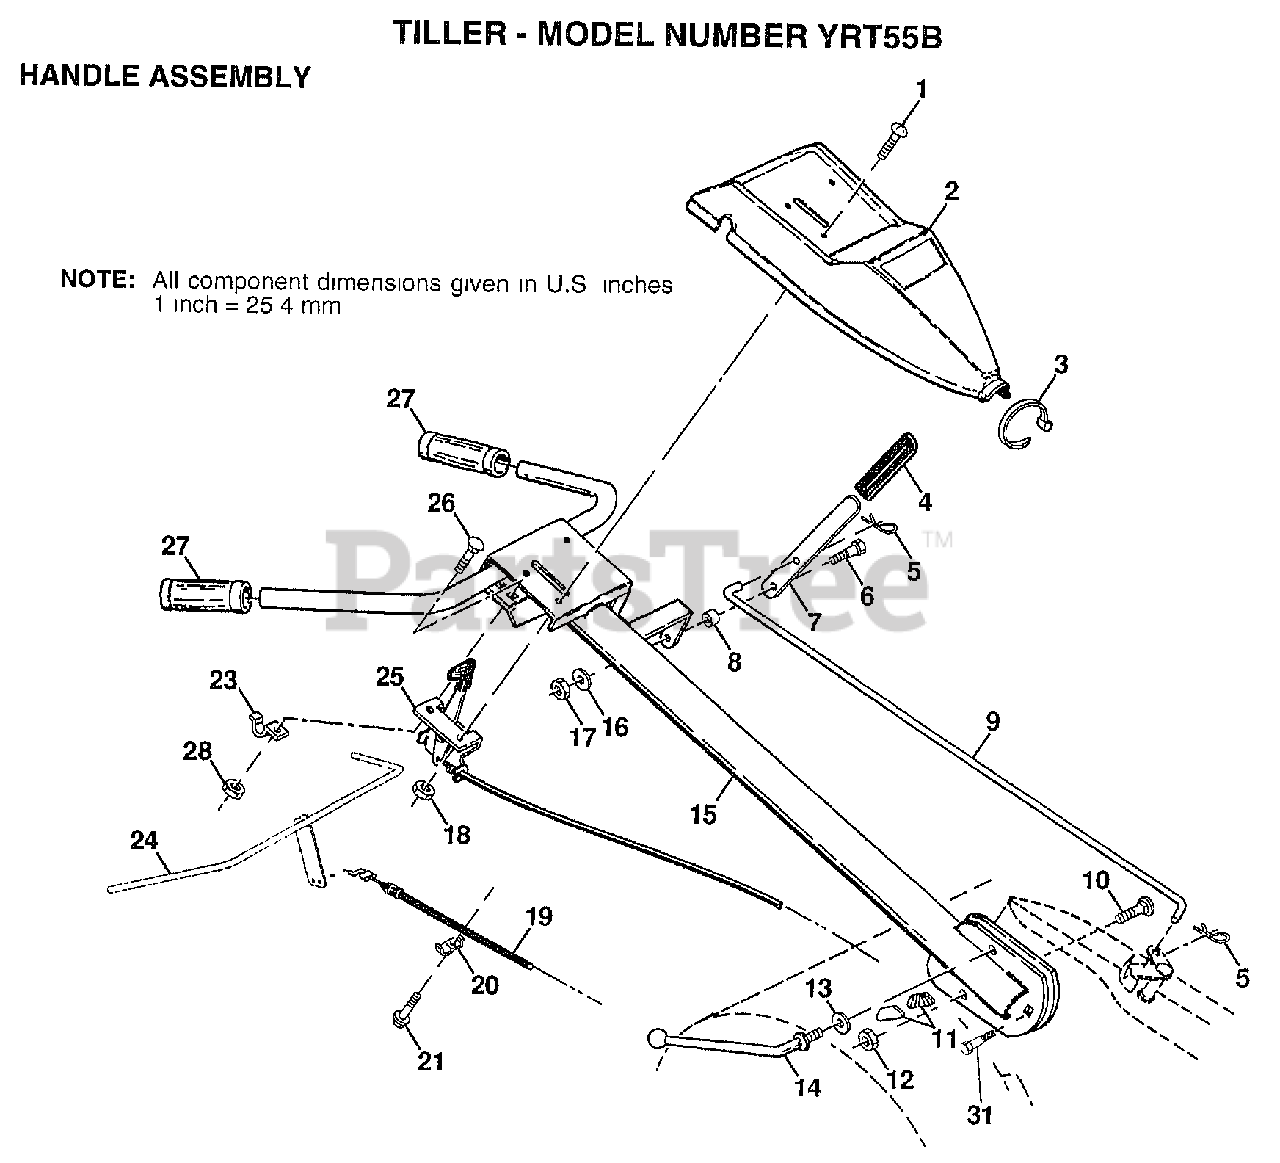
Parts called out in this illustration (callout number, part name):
1	SCREW.PNHD.10-24
2	"PANEL,CONT TI"
3	TIE CABLE CRT
4	GRIP T
6	SHOULDER BOLT ST
7	SHIFT HANDLE CRT
8	GROMMET CRT
9	SHIFT ROD CRT
10	BOLT D
11	LOCK CRT
12	LOCKNUT
13	WASHER CRT
14	LEVER LOCK CRT
16	LOCKWASHER
19	CABLE.CLUTCH
20	CONDIUT CLIP T
22	GRIP BAR CRT
24	BAR ASM CONTROL
25	"CONT,THROTTLE"
26	BOLT
28	NUT
31	BOLT PIVOT
